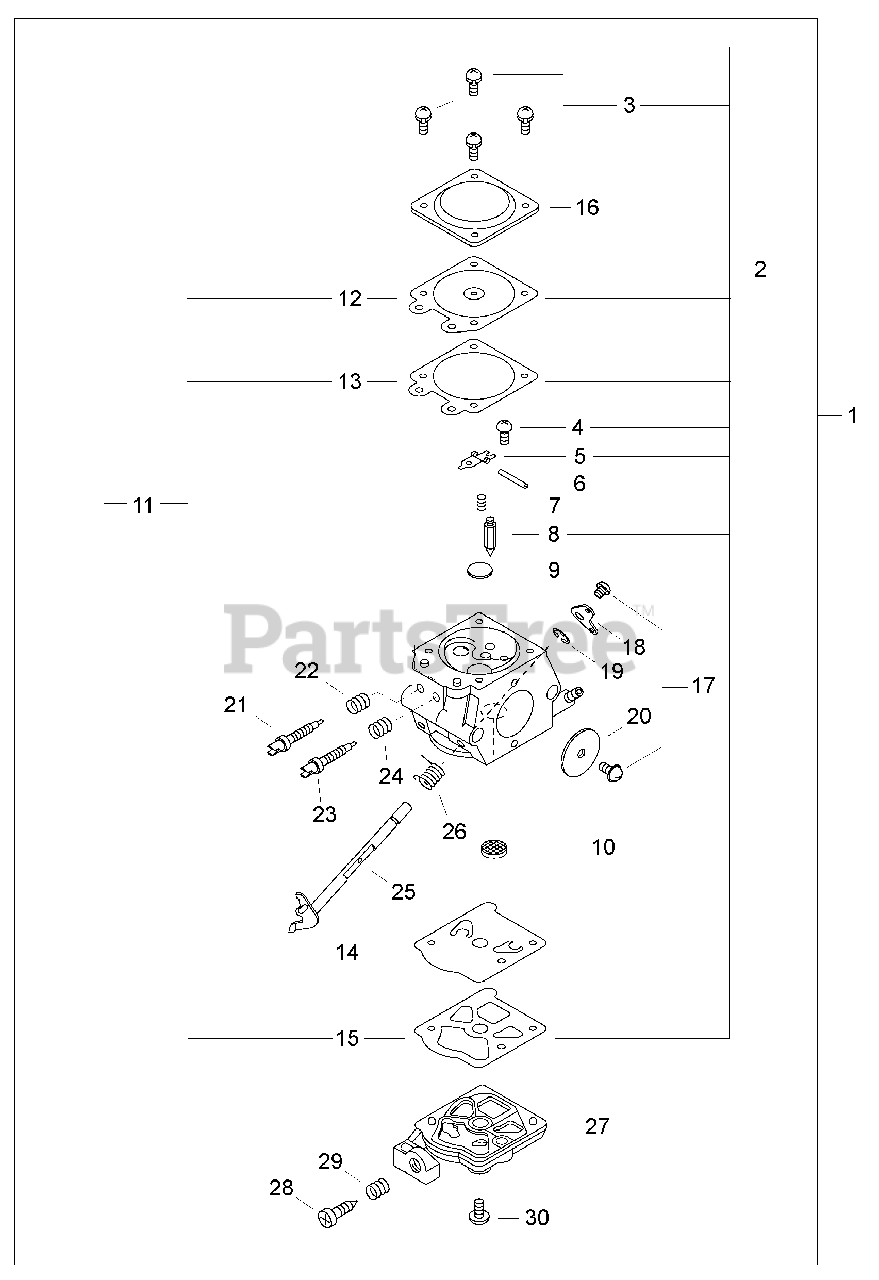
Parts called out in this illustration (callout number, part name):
1	CARBURETOR WT-385A
2	REPAIR KIT
3	SCREW
4	SCREW, METERING LEVER PIN
5	LEVER, METERING
6	PIN, METERING LEVER
7	SPRING
8	VALVE, INLET NEEDLE
9	PLUG, WELCH
10	STRAINER
11	DIAPHRAGM/GASKET KIT
12	DIAPHRAGM, METERING
13	GASKET, METERING
14	DIAPHRAGM, PUMP
15	GASKET, FUEL PUMP
16	COVER, METERING
18	LEVER, THROTTLE
19	RING, RETAINING
20	VALVE, THROTTLE
21	NEEDLE - HIGH SPEED
23	NEEDLE - LOW SPEED
25	SHAFT, THROTTLE
26	SPRING, THROTTLE RETURN
27	COVER, PUMP
28	SCREW, IDLE ADJUST
29	SPRING, IDLE ADJUST
30	SCREW, PUMP COVER
